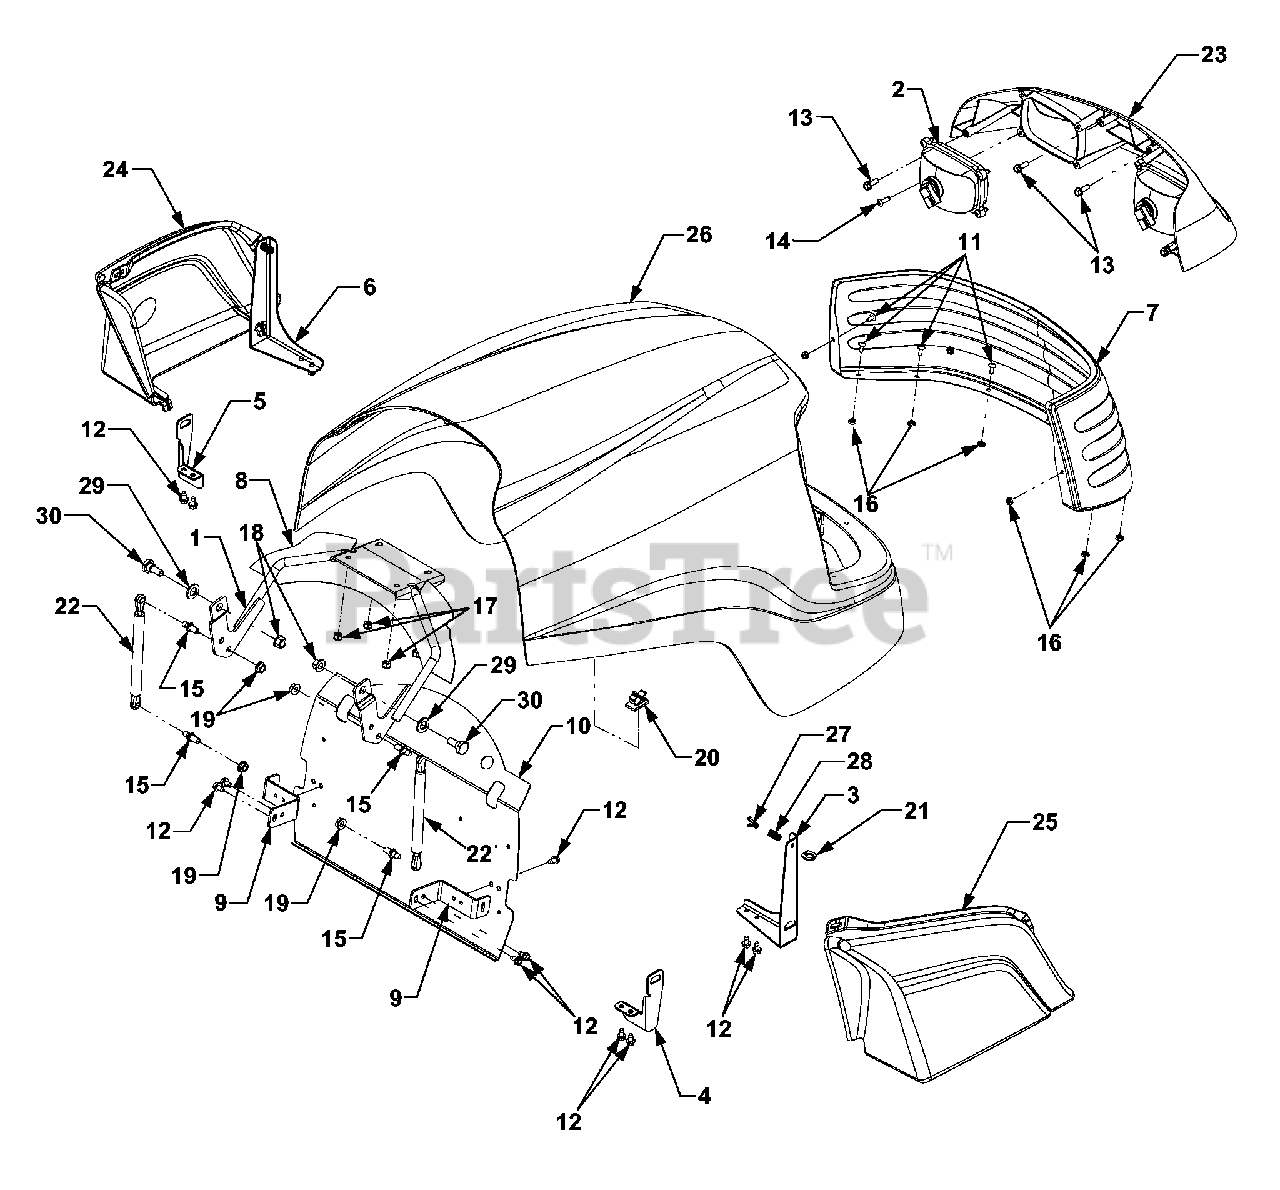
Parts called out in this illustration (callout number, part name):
1	Hinge Assembly, Hood
2	Headlight Assembly
3	Brkt, Side Pnl. Mtg. RH
4	Brkt, Side Pnl. Mtg. RH Rear
5	Brkt, Side Pnl. Mtg. LH Rear
6	Brkt, Side Panel Mtg. LH
10	Shield, Lower Heat
11	Screw, Truss Hd, 10-24 x .5
12	Screw, Hex Wash Hd Tapp 1/4-20 x .5
13	Screw, Hex Wash. Hd. 1/4-20 x .75
14	Screw, Truss Phil. Hd. 12-16 x .75
15	Stud, Cylinder, 5/16-18
16	Nut, Hex Sems, 10-24
17	Nut, Hex Nylon Insert Lock, 1/4-20
18	Nut, Hx Flange Lk, 3/8-16
19	Nut, Hx Flange Lk, 5/16-18
20	Clip, Retaining
21	Latch, 1/4 Turn Panel
22	Cylinder, Gas Spring
23	Bezel, Headlight
24	Panel, Side LH
25	Panel, Side RH
26	Hood, Service Kit
26	Hood
27	Clip, Spring
28	Spring, Compression
29	Washer, Flat, .53 x .93 x .090.
30	Screw, Shlder, .5 x .27 3/8-16
